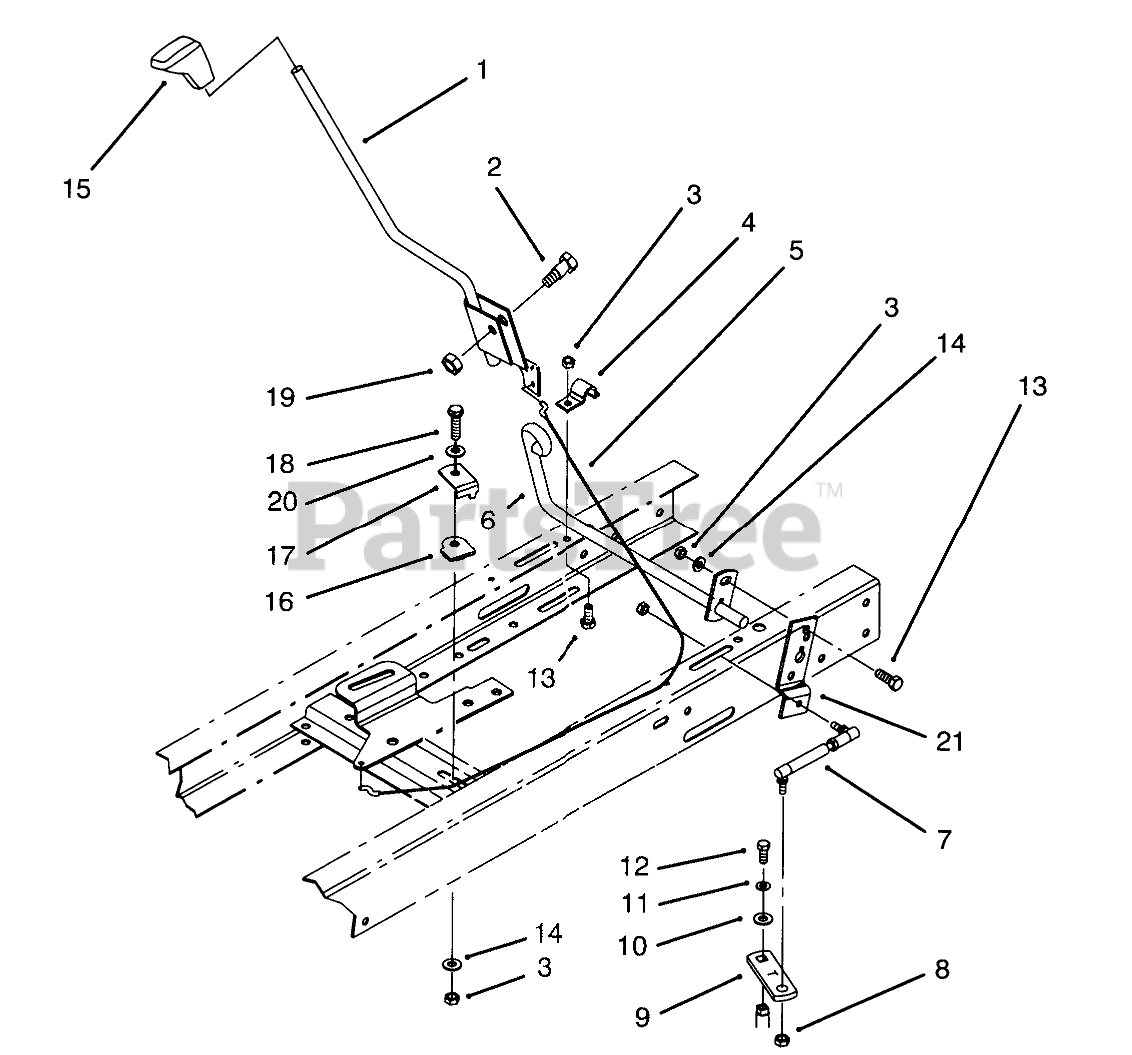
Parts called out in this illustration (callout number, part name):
1	Lever-Shift
2	SHOULDER BOLT
3	NUT-LOCK, NI
4	CLAMP-PIVOT, SHIFT
5	CABLE-CLUTCH
6	SHIFT PIVOT WAB
7	TIE ROD, SHIFT
8	NUT-LOCK
9	LEVER-SHIFT
10	SPACER
11	WASHER-LOCK
12	SCREW-HH
13	SCREW-HH
14	WASHER-PLAIN
15	SHIFT KNOB
16	GUIDE-CABLE
17	KEEPER-CABLE
18	SCREW-CARR
19	NUT-LOCK, NI
20	WASHER-FLAT
21	SHIFT LEVER PIVOTB
